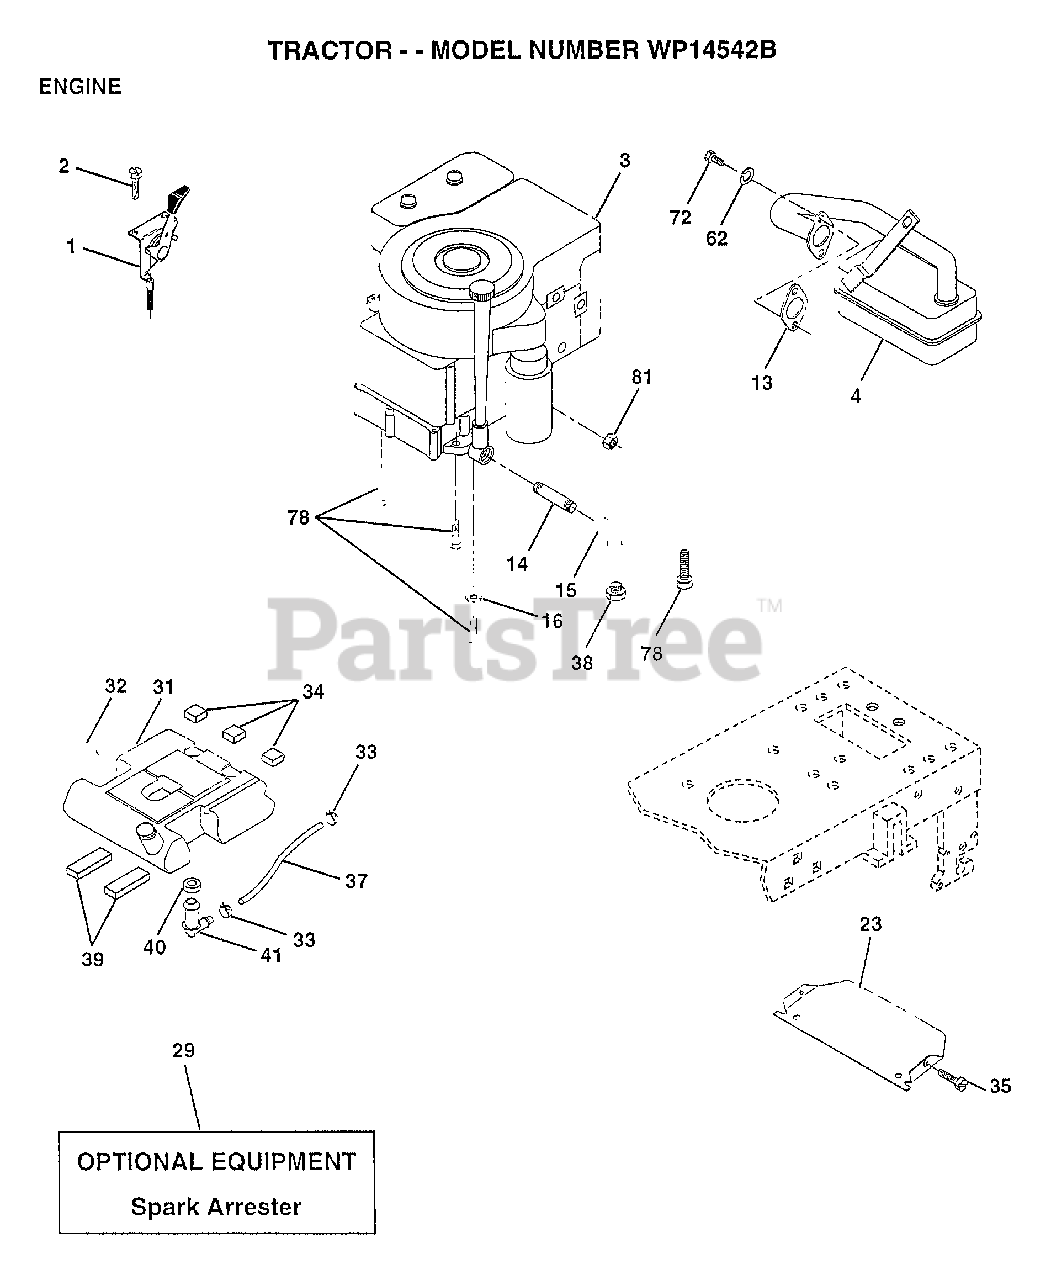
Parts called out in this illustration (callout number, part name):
1	"CONTROL,THROTTLE"
2	SCREW LT
4	MUFFLER
13	GASKET ENG 1 313 LD TIN PLATED
14	PIPE NIPPLE
15	ELBOW
16	LOCKWASHER
23	SHIELD-HEAT
31	TANK FUEL REAR
32	CAP ASM FUEL
33	HOSE CLAMP
34	PAD-SPACER LT
35	SCREW
37	FUEL LINE T
39	PAD IDLER TI
40	BUSHING OUTLET T
62	LOCKWASHER
72	SCREW
78	SCREW
81	NUT
